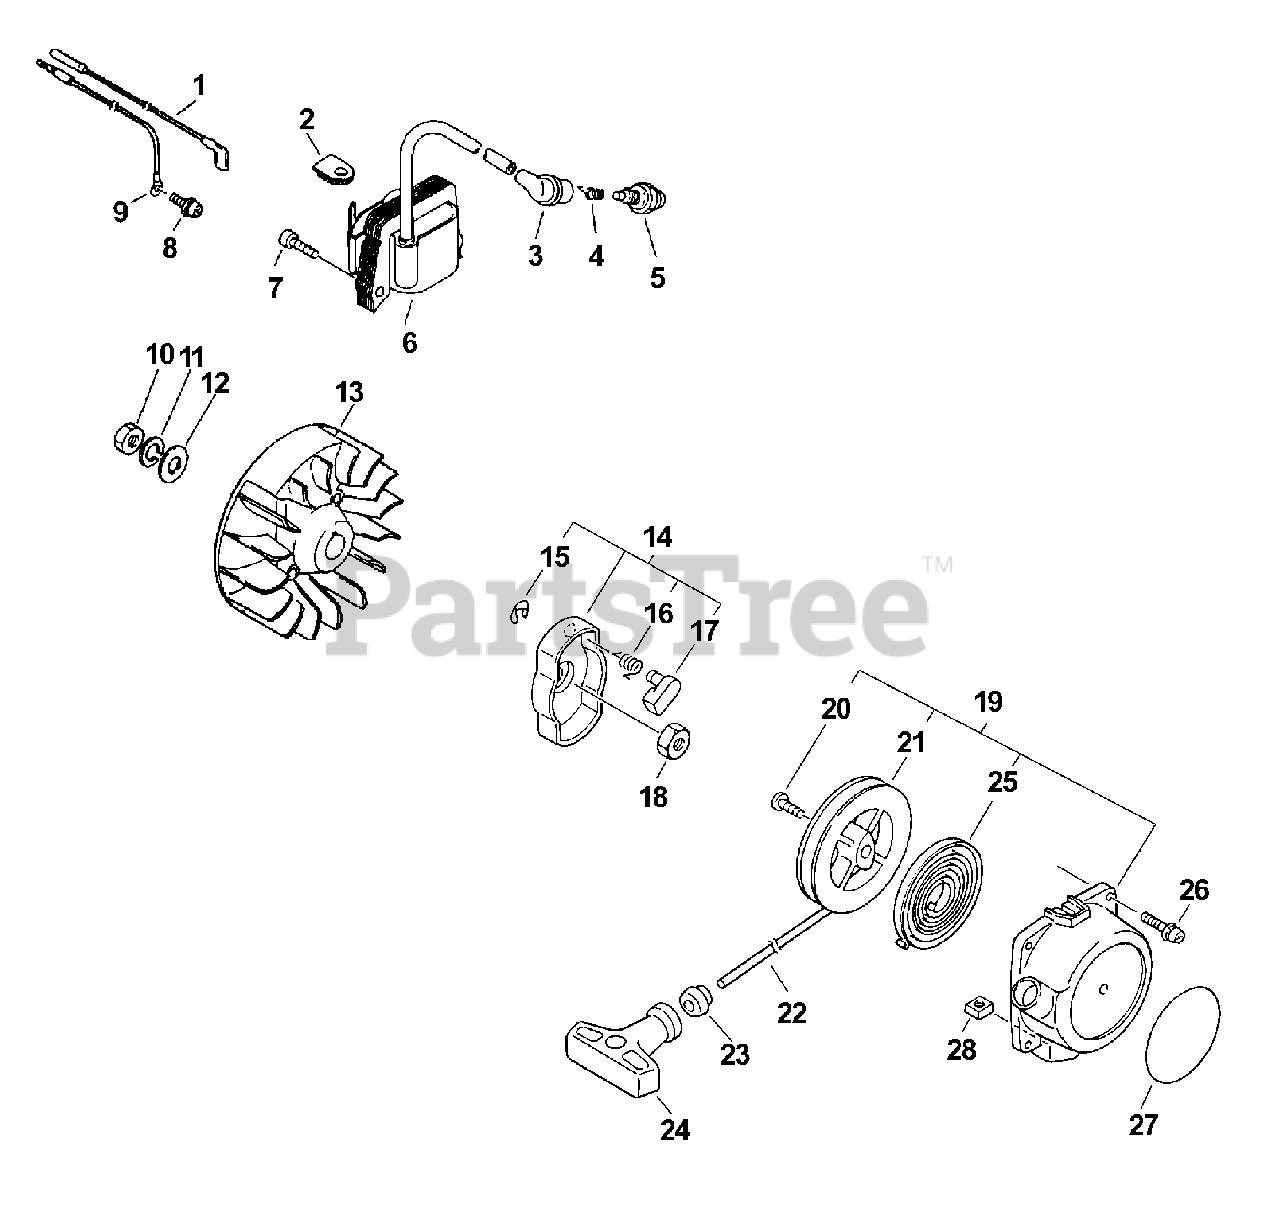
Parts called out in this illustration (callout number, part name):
1	LEAD - IGNITION
2	GROMMET
3	CAP, SPARK PLUG
4	TERMINAL, SPARK PLUG CAP
5	SPARK PLUG -- BPM-7Y
5	SPARK PLUG -- BPMR-7A
6	COIL, IGNITION
7	SCREW - 5X20
8	SCREW - 5X10
9	LEAD - GROUND
11	LOCKWASHER - 8
12	WASHER - 8
13	FLYWHEEL
14	STARTER PAWL ASSY
15	RING, RETAINING - 4
16	SPRING, RETURN
17	PAWL, STARTER
19	STARTER ASSY
21	REEL, ROPE
22	ROPE, STARTER
23	GUIDE, ROPE
24	GRIP, STARTER
25	SPRING, REWIND
26	SCREW - 4X14
27	LABEL - ECHO
28	NUT - 5 -- SQUARE
